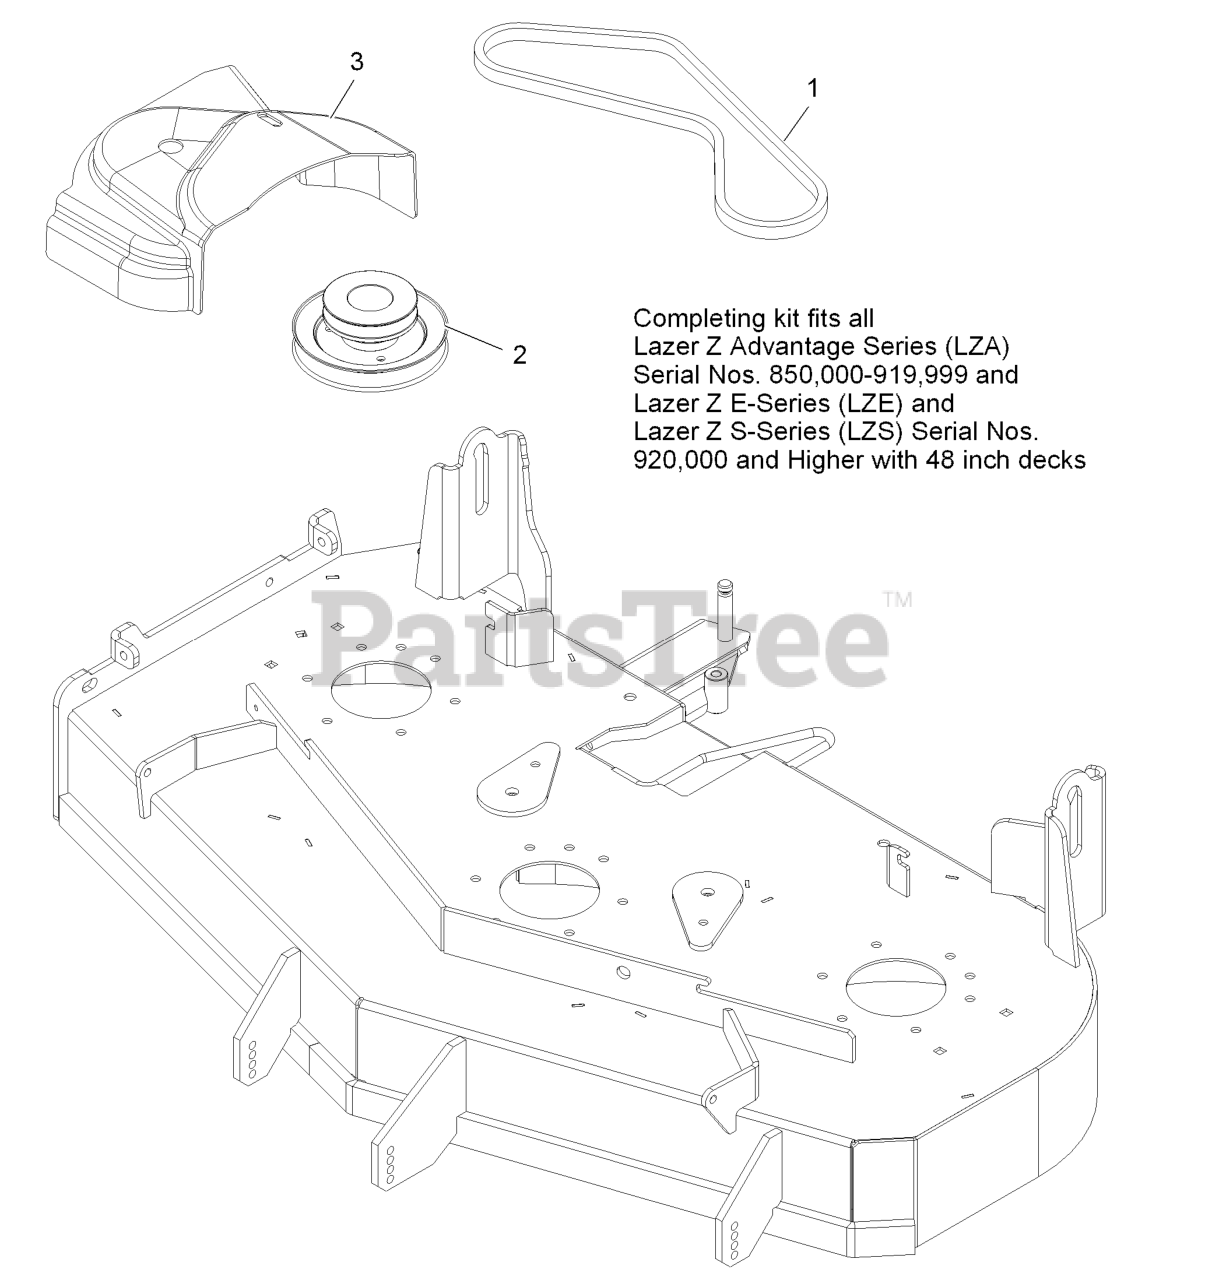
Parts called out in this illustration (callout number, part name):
1	BELT-BLOWER
2	JACKSHAFT-UV DRIVE, 484 S
3	COVER,BELT UV 48
